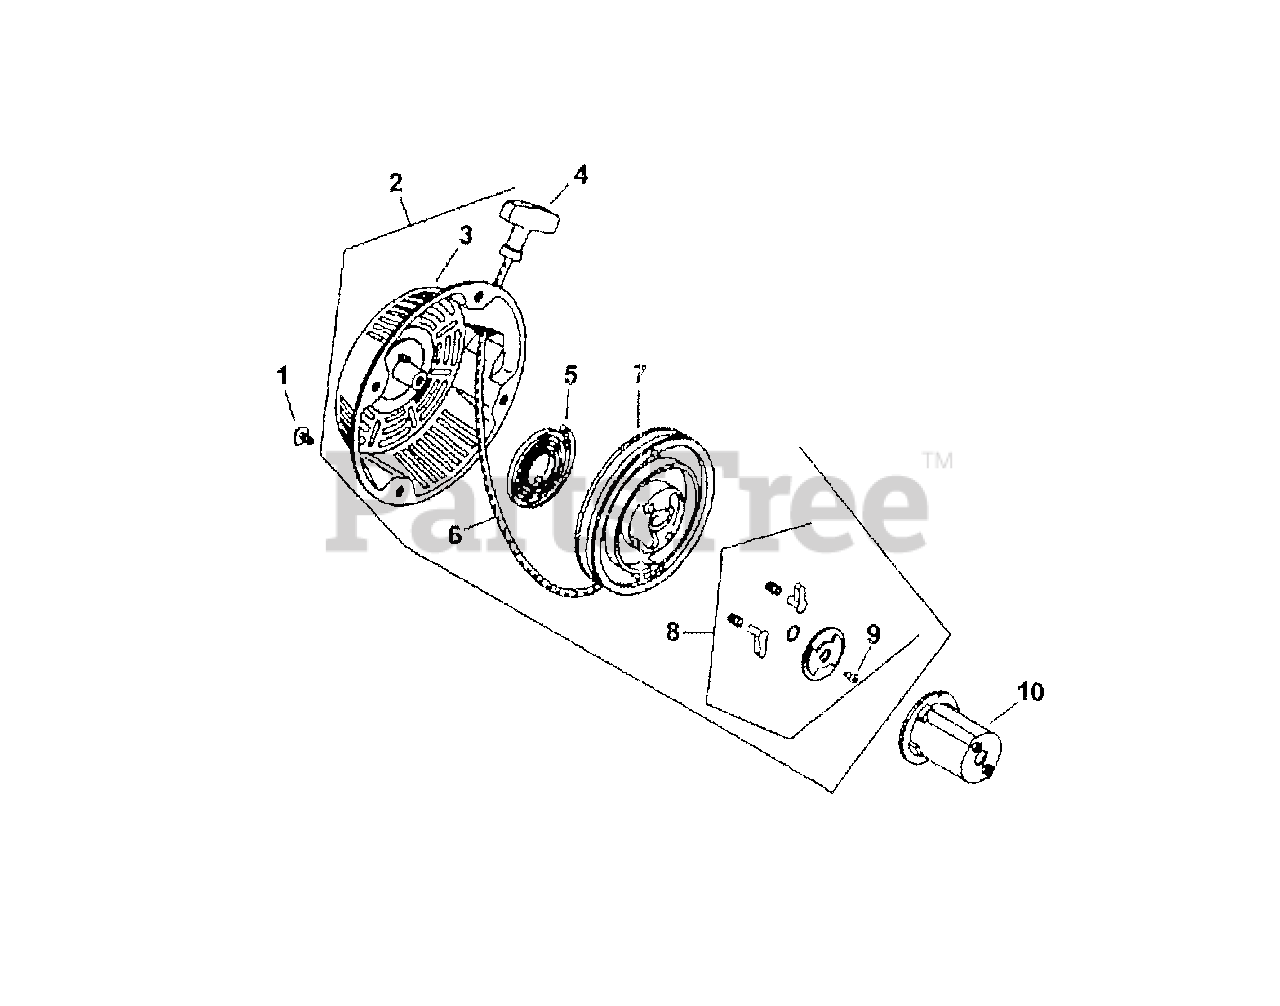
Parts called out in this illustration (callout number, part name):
2	Recoil Starter
3	Housing Assembly
4	Handle, Starter
5	Spring, Recoil
6	Rope, Starting
8	Kit, Pawl Repair
10	Cup, Starter Drive
